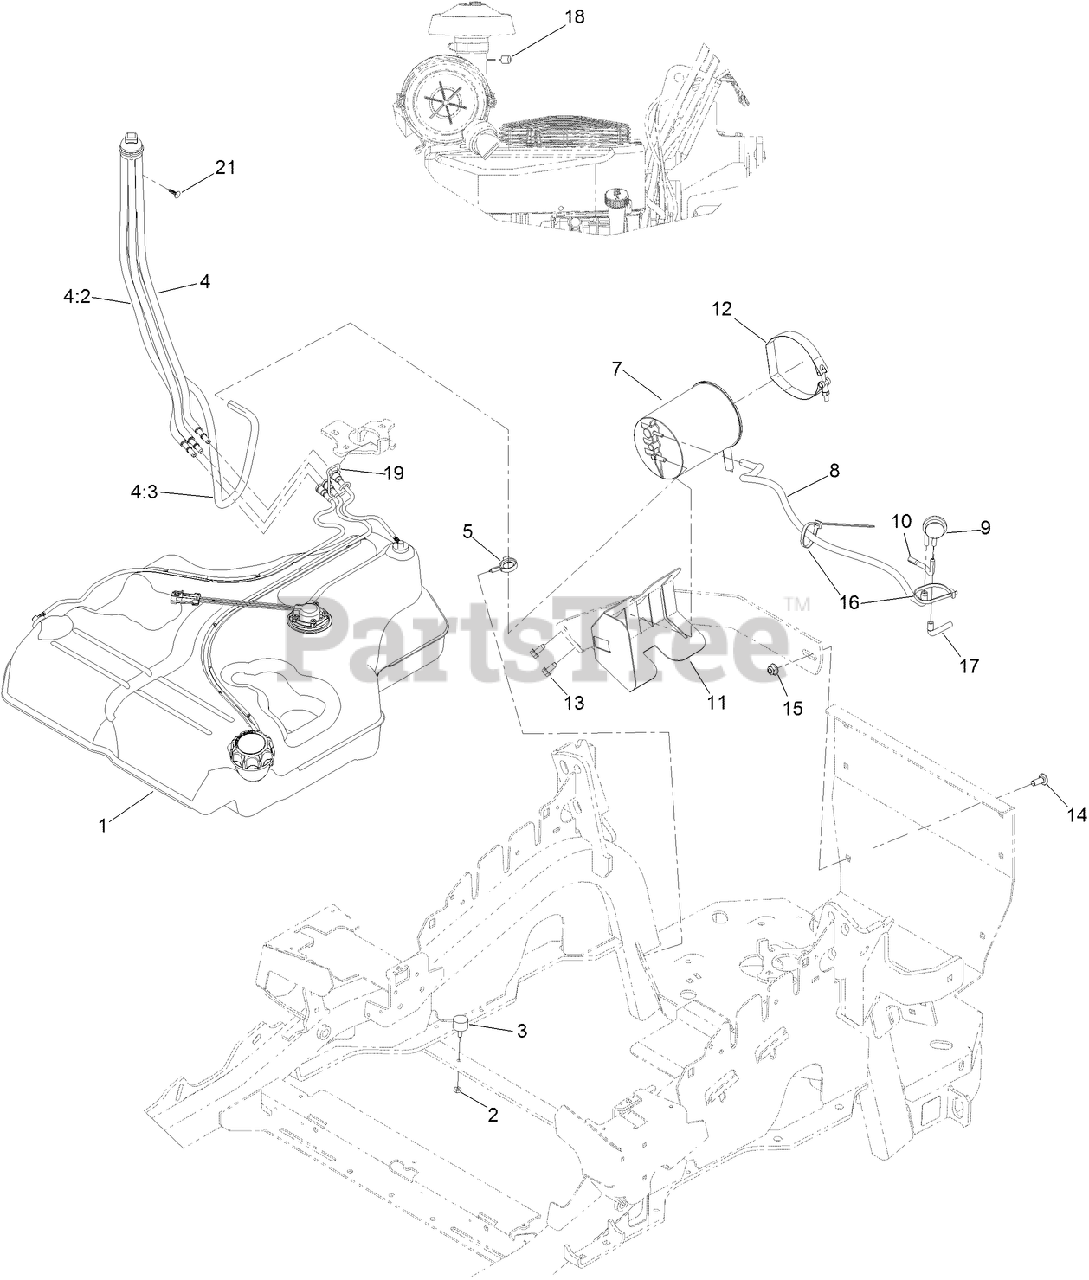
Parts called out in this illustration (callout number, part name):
1	FUEL TANK ASM
2	NUT-JAM
3	BUMPER
4	FUEL MANIFOLD VENT ASM
4:2	HOSE-FUEL
4:3	HOSE-FUEL
5	CLAMP-HOSE
7	CANISTER-CARBON, 1200CC
8	HOSE-VENT, FORMED
9	VALVE-CONTROL, VACUUM
10	HOSE-VENT, FORMED
11	MOUNT-CANISTER
12	CLAMP, T-BOLT
13	SCREW-HWHTF
14	SCREW-CARR
15	NUT-HF, NI
16	TIE-PLASTIC
17	HOSE-VENT, FORMED
18	PLUG-PORT
19	RETAINER-LINE, VAPOR
21	PLUG-PLASTIC
